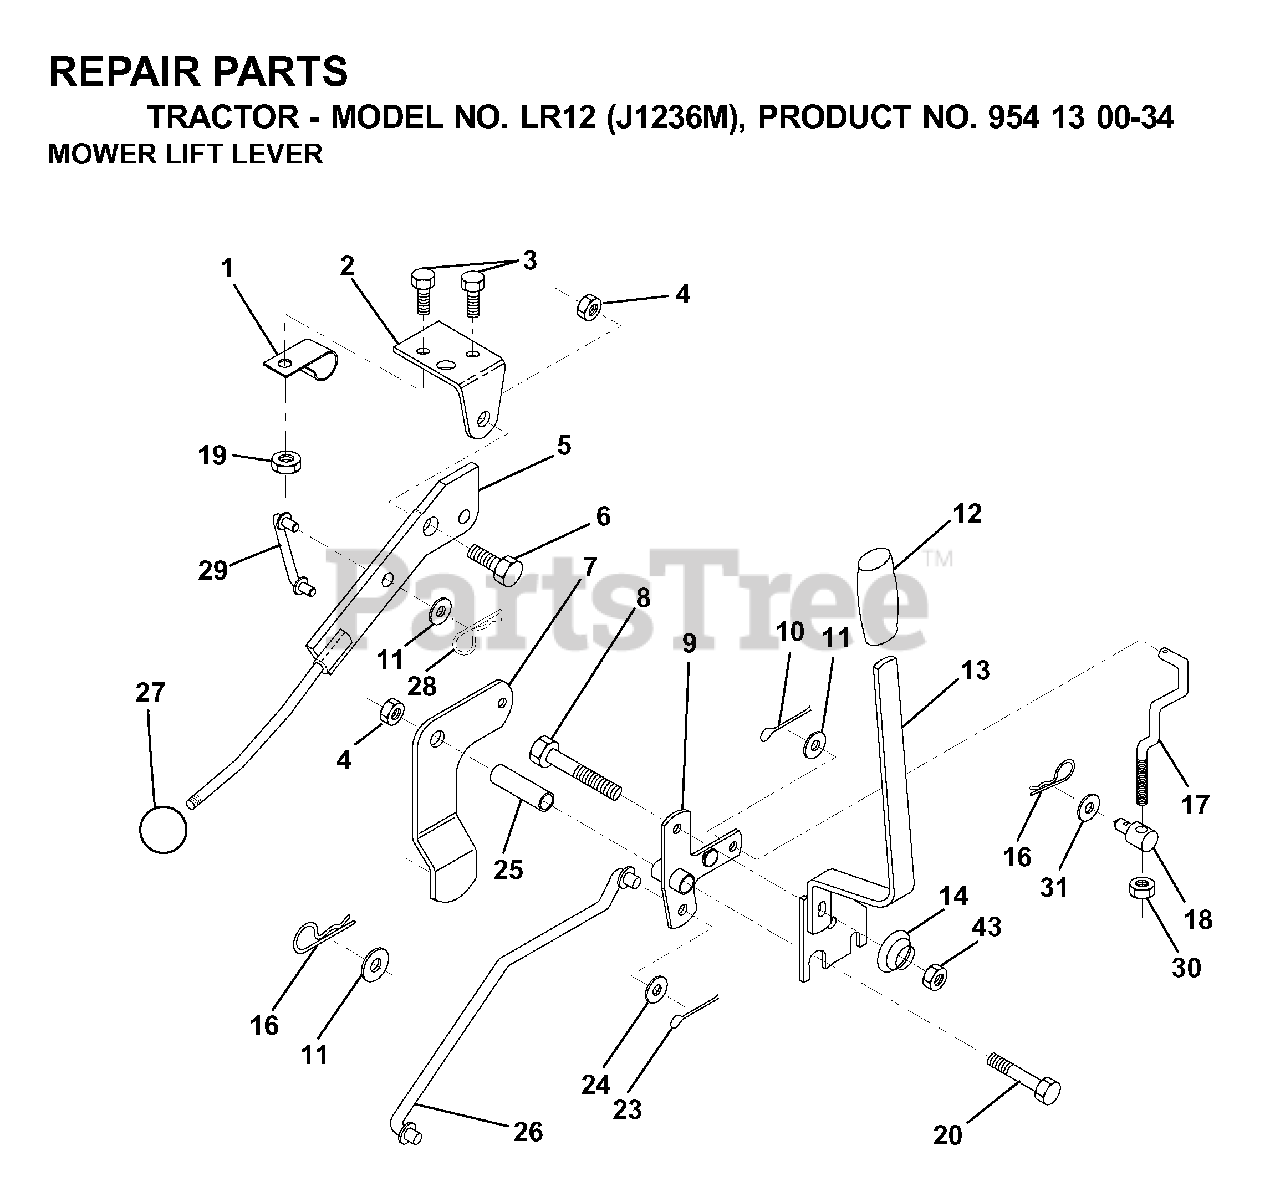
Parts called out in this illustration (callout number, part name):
1	CLIP,INSULATOR
2	BRKT CLUTCH
4	LOCKNUT
5	CLUTCH LEVER
6	BOLT, SHOULDER LT
7	ASSEMBLY MOWER CLUTCH ARM
9	BELLCRANK,LIFT
10	COTTER PIN
12	GRIP HANDLE
13	LIFT HANDLE ASSY
14	SPRING COMPRESSIO
16	SPRING TI
17	LINK LIFT FRT
19	NUT.CROWNLOCK.1/4
23	PIN COTTER
24	WASHER GT
25	TUBE SPACER
27	KNOB
28	RETAINER M
29	LINK MOWER CLUTCH
30	NUT
43	NUT LOCK FLG 3/8-16 UNC
